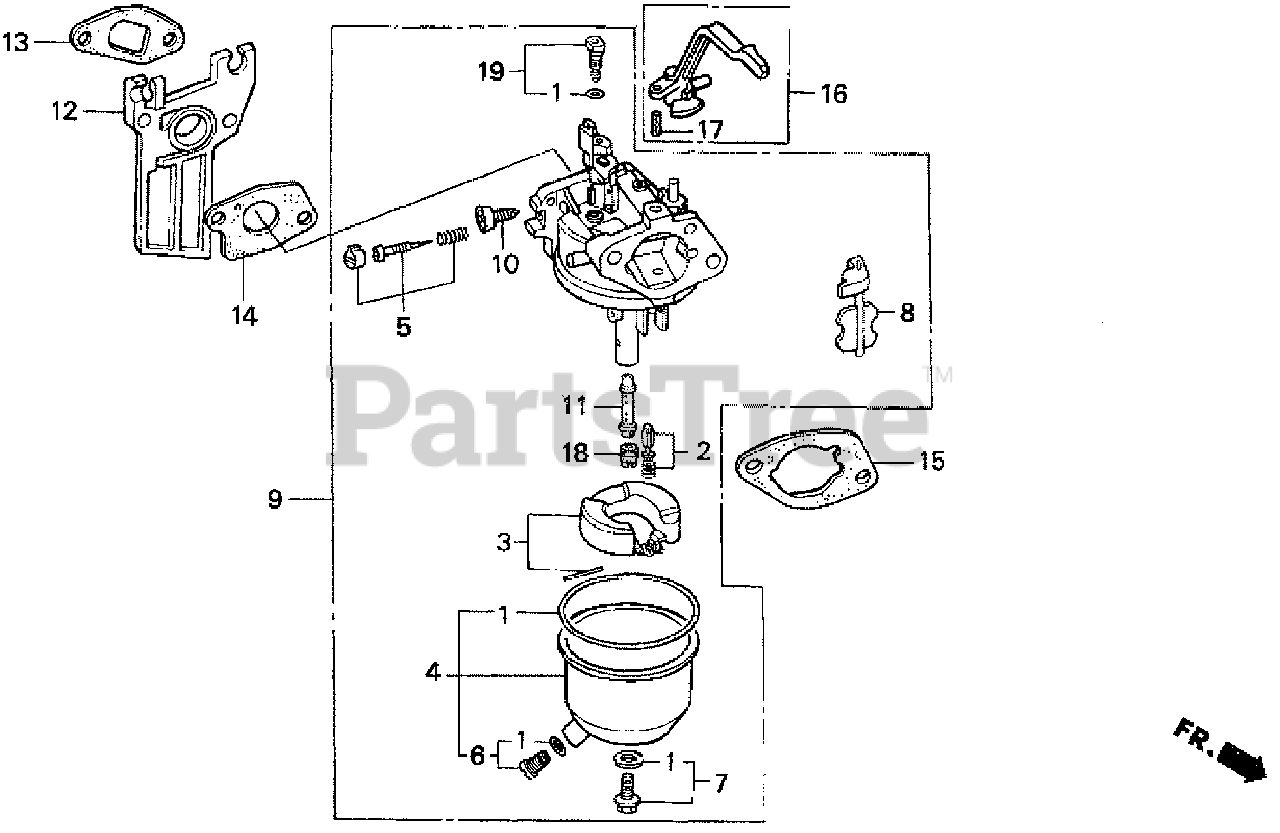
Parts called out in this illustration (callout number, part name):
1	GASKET SET
2	VALVE SET, FLOAT
3	FLOAT SET
4	CHAMBER SET, FLOAT
5	SCREW SET
6	SCREW SET, DRAIN
7	SCREW SET B
8	CHOKE SET
9	CARBURETOR ASSY. (BE67A B)
10	SCREW, THROTTLE STOP
11	NOZZLE, MAIN
12	INSULATOR, CARBURETOR
13	GASKET, INSULATOR
14	GASKET, CARBURETOR
15	GASKET, AIR CLEANER
16	LEVER, CHOKE
17	PIN, SPRING (2X12)
18	JET, MAIN (#70)
18	JET, MAIN (#72)
18	JET, MAIN (#75)
19	JET SET, PILOT (#35)
